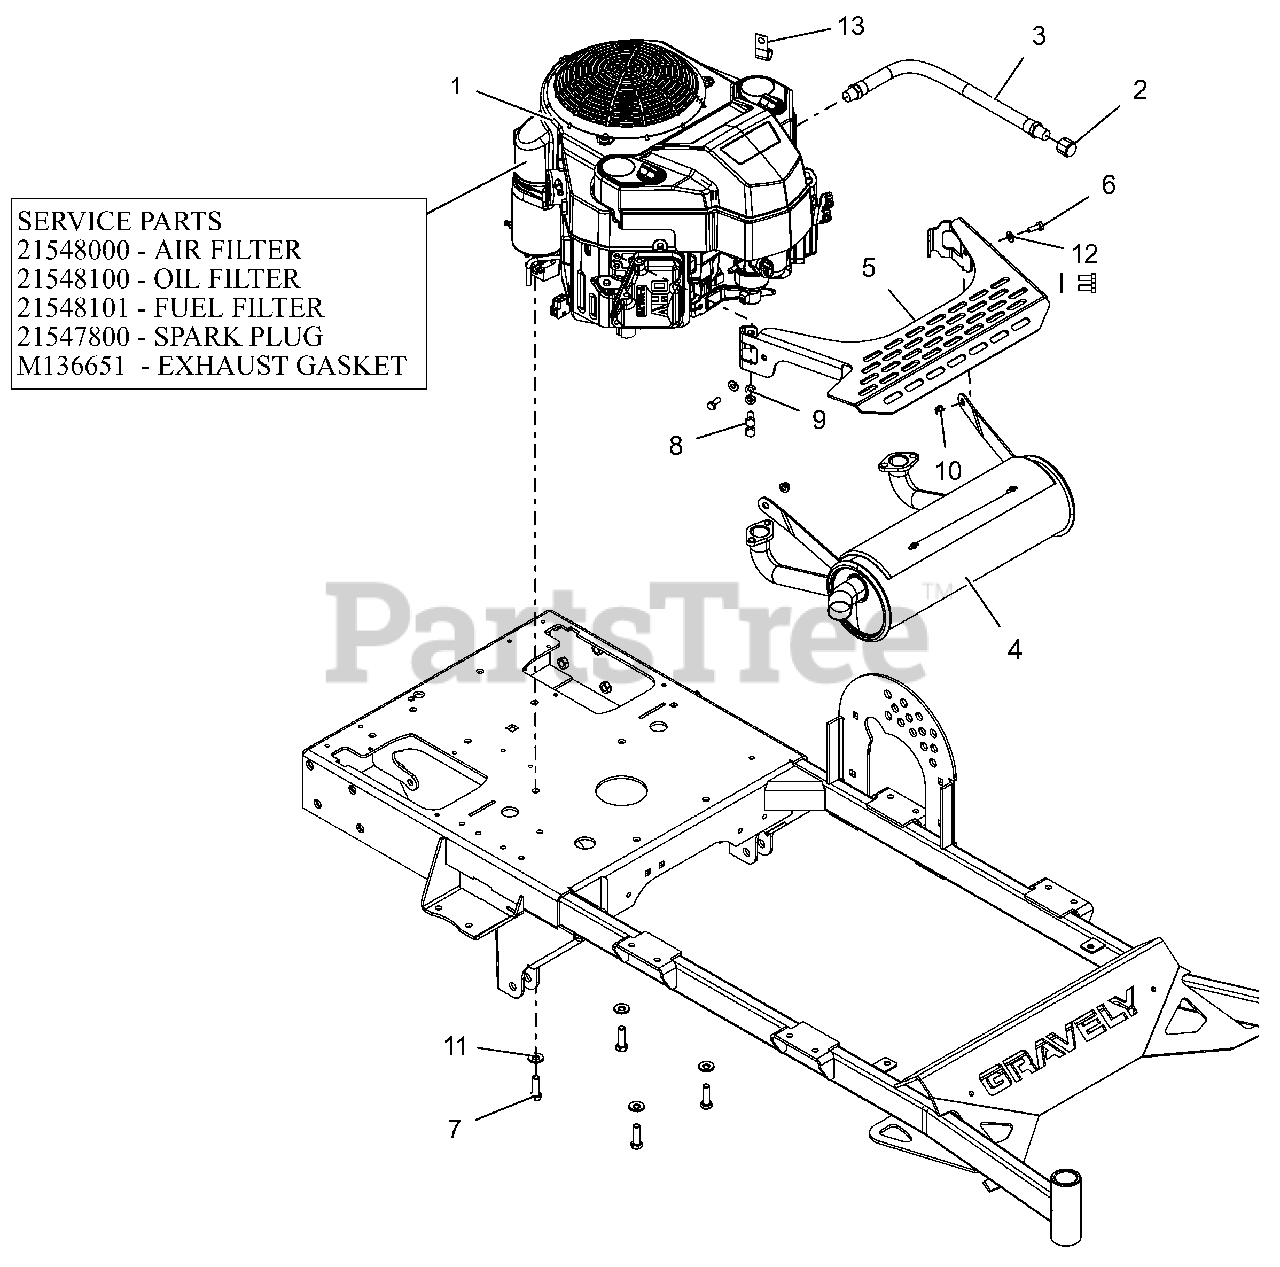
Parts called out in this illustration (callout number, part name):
1	ENGINE, KAWASAKI FS481
1	AIR FILTER, KAWASAKI FR
1	OIL FILTER, KAWASAKI FR
1	FUEL FILTER-KAWASAKI FR
1	SPARK PLUG, KAWASAKI FR
1	GASKET, MUFFLER #
2	PIPE CAP 3/8 NPT FEMALE
3	DRAIN, M20 OIL
4	MUFFLER, KAW FS PROWALK
5	KIT, MUFFLER SHIELD W DECALS
6	@BLT-HEX .25-20X.75 GR5 YWZC
7	BLT-HEX.38-16X1.25 G5YZ NYTORQ
8	@BLT-HEX M8-1.25X20 YWZC
9	@WSHR-LK .31X.078 REG YWZC
10	@NUT-LK-NYL-FLG .25-20 YWZC
11	WASHER, 3/8" SPRING DISC
12	@WSHR-FL-STL.281X.62X.065 YWZC
